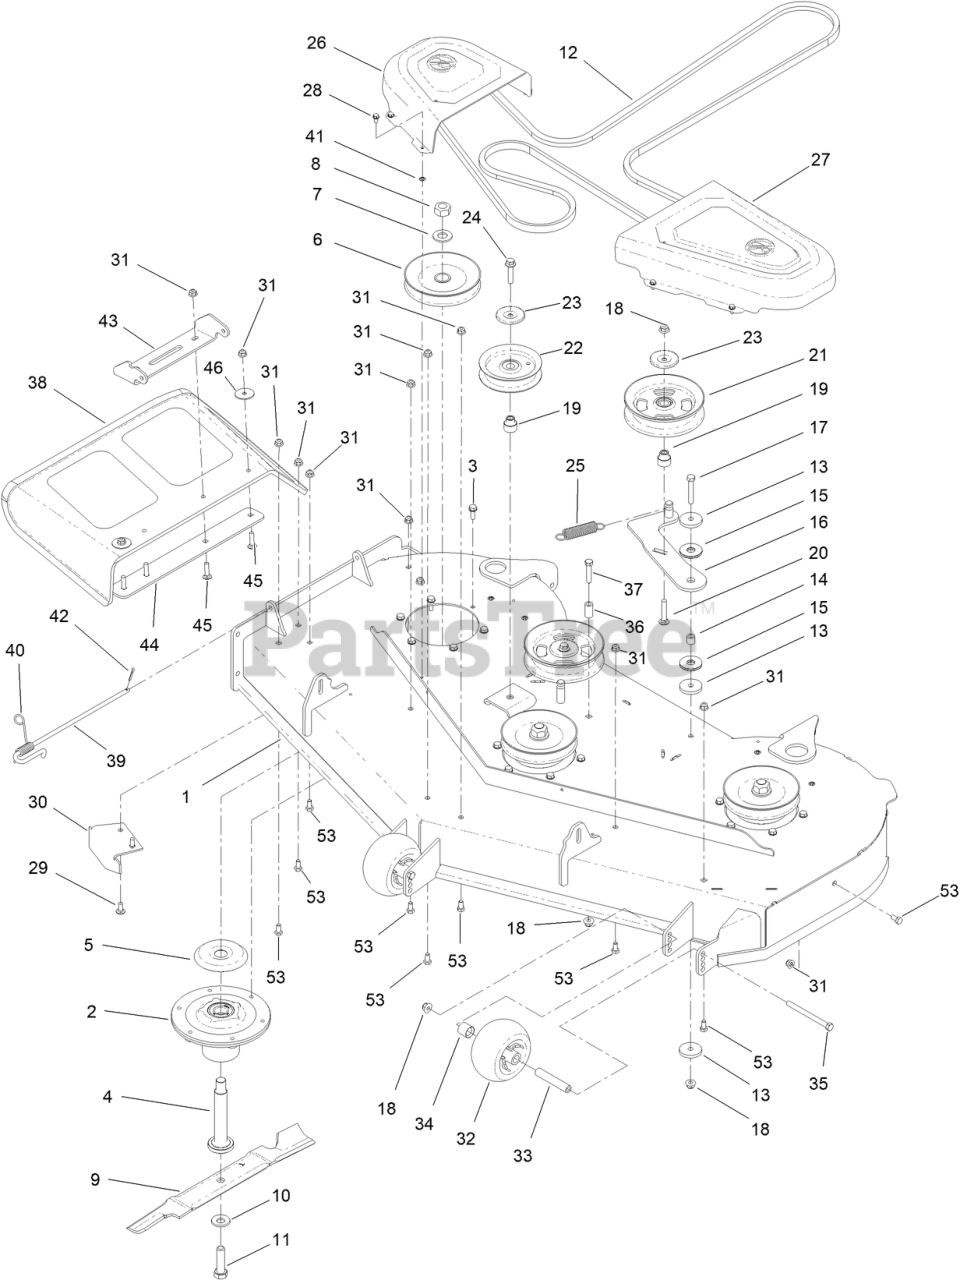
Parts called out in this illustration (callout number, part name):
1	DECK ASM-54"
2	SPINDLE ASM
3	SCREW-TAPTITE
4	SHAFT-SPINDLE
5	SHIELD-BEARING
6	PULLEY
7	WASHER
8	NUT-HEX
9	BLADE - HI FLOW, 18.75 IN
10	WASHER-BELLEVILLE
11	SCREW-BLADE
12	BELT-V
13	WASHER-PLAIN
14	BUSHING-IDLER
15	WASHER-FRICTION, COMPOSITE
16	IDLER ARM ASM
17	SCREW-HH
18	NUT-HF, NI
19	BUSHING-IDLER
20	SCREW-CARR
21	PULLEY-IDLER, FLAT
22	PULLEY-IDLER, FLAT
23	SHIELD-DUST
24	SCREW-HHF
25	SPRING-EXTENSION
26	COVER-BELT, RH
27	COVER-BELT, LH
28	SCREW-HWH
29	SCREW-CARR
30	BAFFLE-CUTOFF
31	NUT-HF, NI
32	ROLLER-SCALP, ANTI
33	TUBE-SPANNER
34	SPACER-AXLE, REAR
35	SCREW-HH
36	SPACER-FENDER
37	SCREW-HH
38	DEFLECTOR
39	PIN-CHUTE
40	SPRING-TORSION
41	NUT-RETAINING
42	PIN-COTTER
43	BRACKET UPPER, DEFLECTOR
44	PLATE-DEFLECTOR
45	SCREW-CARR
46	WASHER-FLAT
53	SCREW-HH
